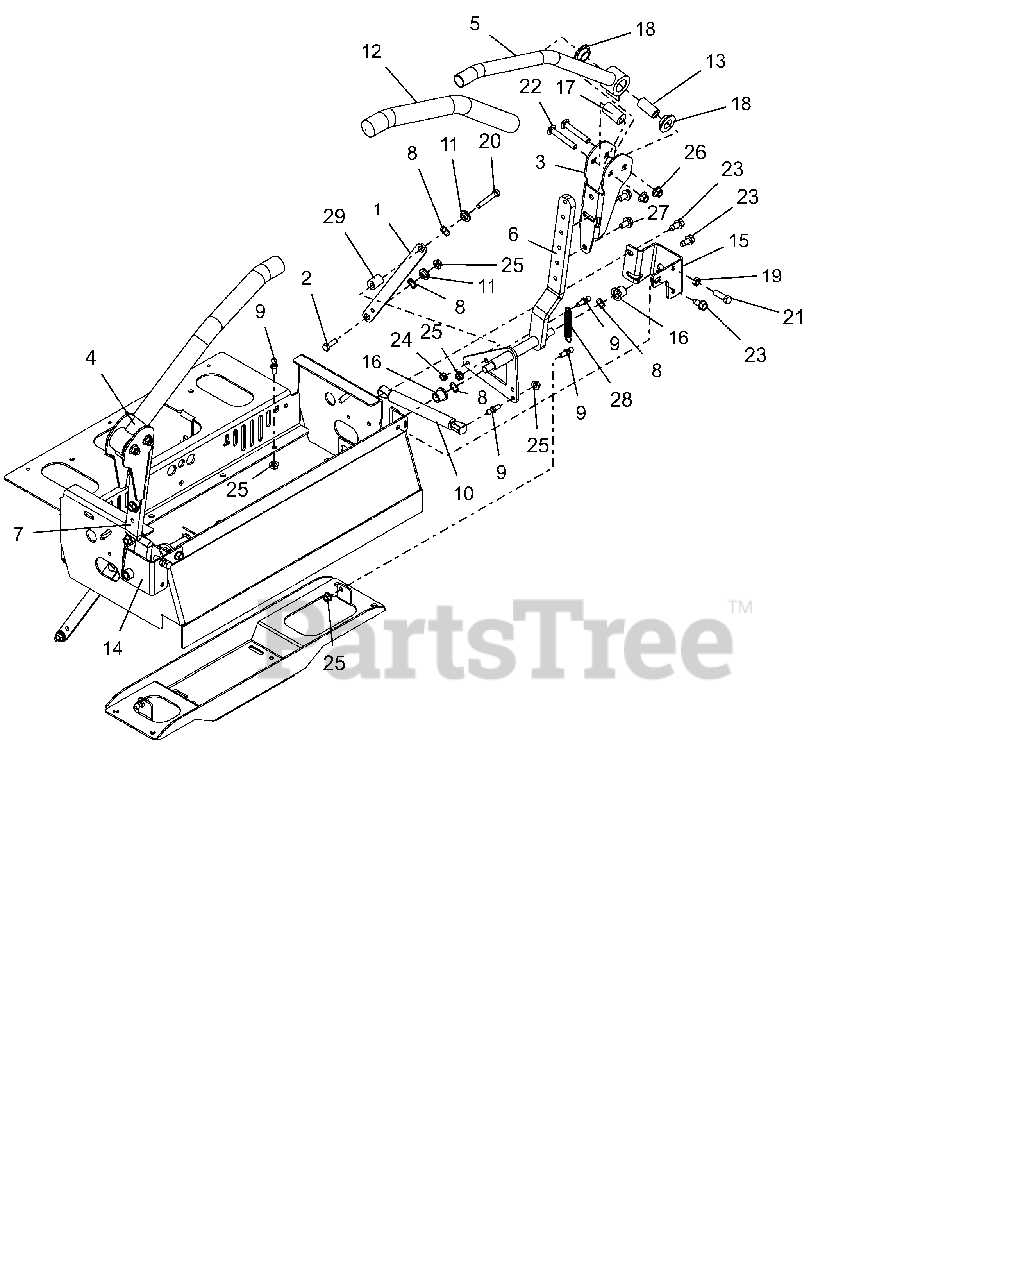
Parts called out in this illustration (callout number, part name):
1	LINK, STEERING CONTROL
2	@BLT-HEX .31-18X1.00 GR5 YWZC
3	ADJ UPPER CONTROL ARM BRKT-BLK
4	WLDMT, CONTROL HANDLE- BLK
5	WLDMT, CONTROL HANDLE- BLK
6	WLDMT, LH LOWER CONTROL ARM
7	WLDMT, RH LOWER CONTROL ARM
8	WAVE WASHER .531X.781X.125FH
9	STUD- BALL
10	DAMPER
11	BSHG-FLG .32X.500X.344X.880
12	GRIP, HANDLEBAR
13	SPACER, STEERING ARM
14	PT200/400 RH CNTRL STP BRK-RED
15	PT200/400 LH CNTRL STP BRK-RED
16	BHSG-FLG .500X.750X.750X.125
17	BSHG, ECCENTRIC.406X.875X1.625
18	BSHG-FLG .762X1.48X.44 NYL
19	NUT-HEX-JAM .375-16 YWZC
20	@BLT-HEX .31-18X2.00 GR5 YWZC
21	@BLT-HEX .38-16X1.25 GR5 YWZC
22	BLT-RDHDSQSHK, 38-16X2.50 G5YZ
23	@SCR-TAP .38-16X.75 HWH TR YWZ
24	@NUT-LK-CTR .31-18 YWZC
25	@NUT-LK-TOP-FLG .31-18 YWZC
26	@NUT-LK-NYL-FLG .38-16 YWZC
27	BLT, SCRHFWH .375-16X.625 YWZC
28	SPRING,EXT,.061X.50X3.0
29	ECCENTRIC
